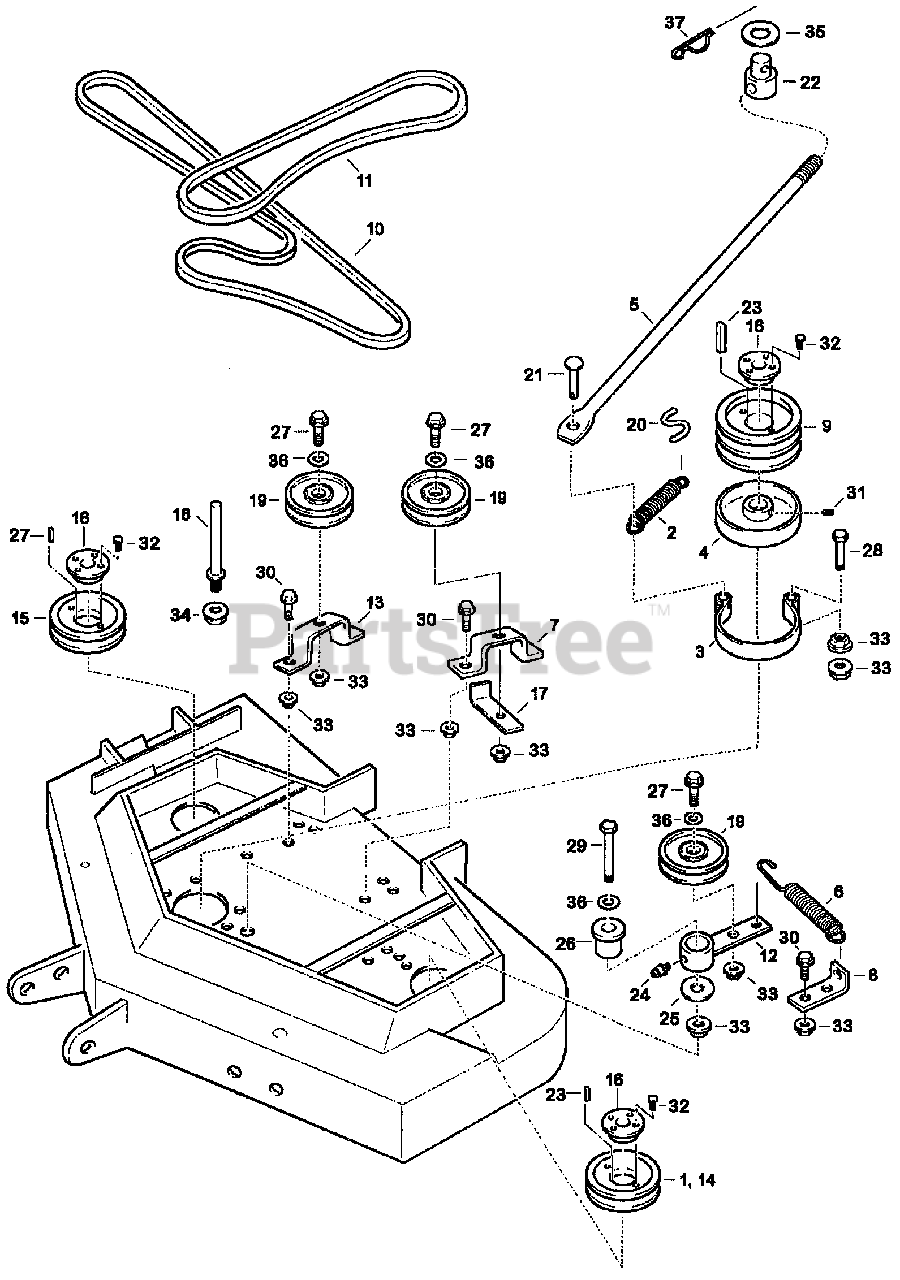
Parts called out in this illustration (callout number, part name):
2	SPRING, TENSIONER
3	BAND, BRAKE
4	DISK, FRICTION
5	ROD C, P.T.O.
6	SPRING, TENSION
6	SPRING, TENSIONER ARM
7	BRACKET, TENSIONER
8	PLATE, SPRING HOOK
9	PULLEY, DRIVEN
10	V-BELT, BLADE
11	V-BELT, DECK
12	ARM, IDLER
13	BRACKET, IDLER
14	PULLEY A, BLADE
15	PULLEY B, BLADE
16	BORE BUSH (25MM)
17	GUIDE A, BELT
18	GUIDE C, BELT
19	PULLEY, TENSION
20	CLIP, SPRING
21	PIN, CLEVIS (5/16")
22	PIN, PIVOT
23	KEY, SQUARE (1/4"X1/4"X1")
24	NIPPLE, GREASE
25	WASHER (1" MACH)
25	BUSHING (1")
26	BUSHING, PIVOT
